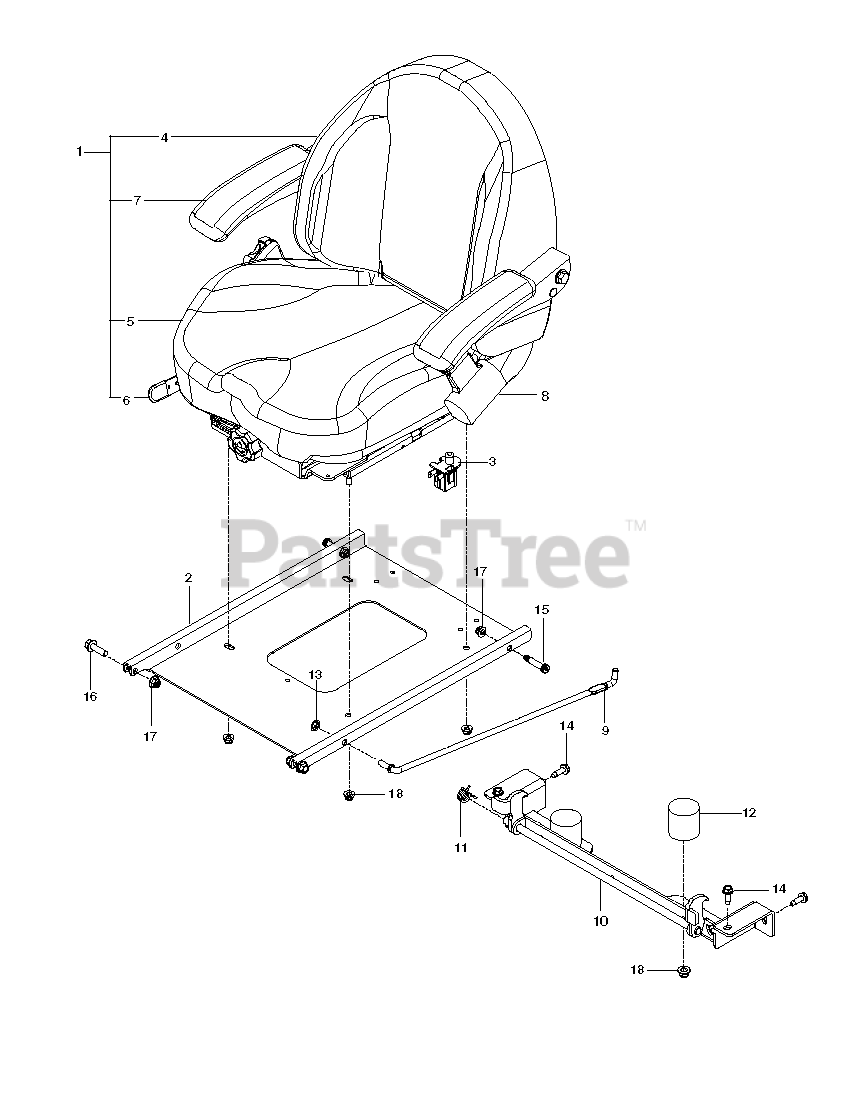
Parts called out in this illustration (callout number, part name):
1	SEAT, 1110 SUSPENSION
2	PAN, SEAT, BLACK
3	SEAT SWITCH
4	COVER, BACK
5	COVER KIT, CUSHION
7	ARMREST, LT
8	Seat Belt, Retractable
10	LATCH.SEAT.BLACK
11	SPRING, TORSION
12	BUMPER, RUBBER
13	NUT 3/8 PALNUT RTNG BLK PHOS
14	RP BLT 5/16-18 X 1 THRD FORM D
15	BOLT, SHOULDER 3/8 X 1.25
16	HHFS 3/8-16 X 1.25 GD 5
17	NUT 3/8-16 HEX FLG NYLOC ZD
18	5/16-18 NYLOC FLANGE NUT
